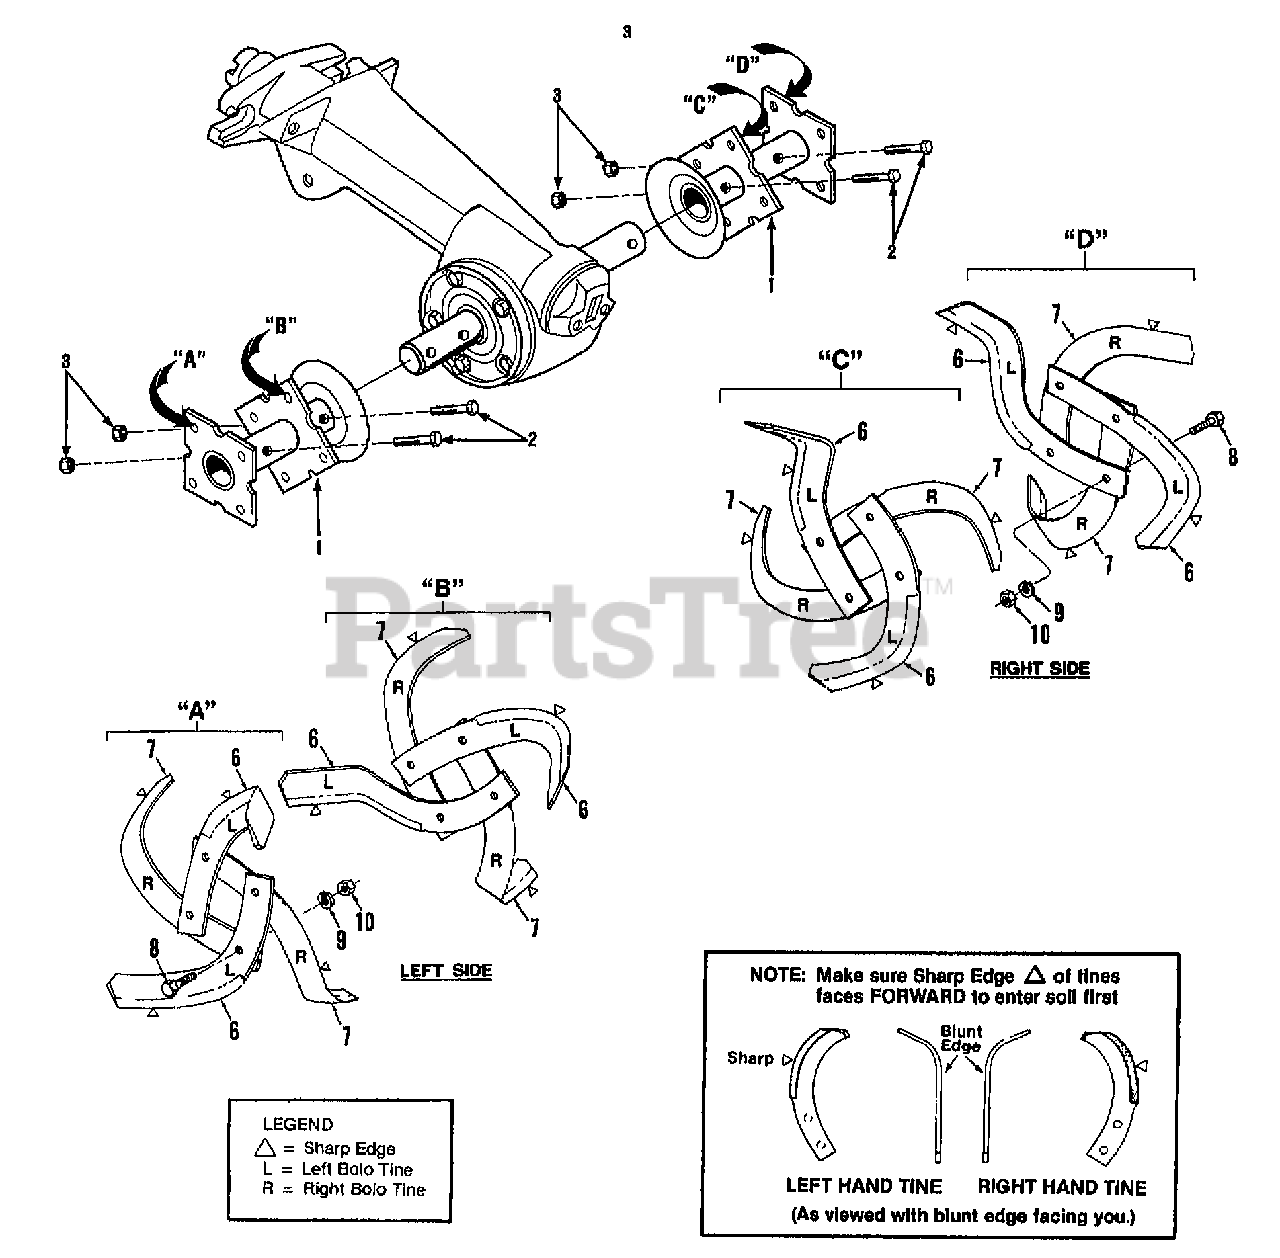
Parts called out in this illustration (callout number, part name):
1	HOLDER-TINE HORSE (RED)
2	SCR-HH 3/8-16X2.00 G8
3	NUT-H/LK 3/8-16
4	THIS REF. NO. NOT USED
5	THIS REF. NO. NOT USED
6	TINE-BOLO LT W/HDW(INCL. TWO EACH OF REF. NO.'S 8,9 AND 10)
7	TINE-BOLO RT W/HDW(INCL. SAME HARDWARE AS REF. NO.6)
8	SCR-HH 3/8-16X1.0 G5 ZP
9	WASHER-LK .375 @ DEPL
10	NUT-HEX 3/8-16 ZP
